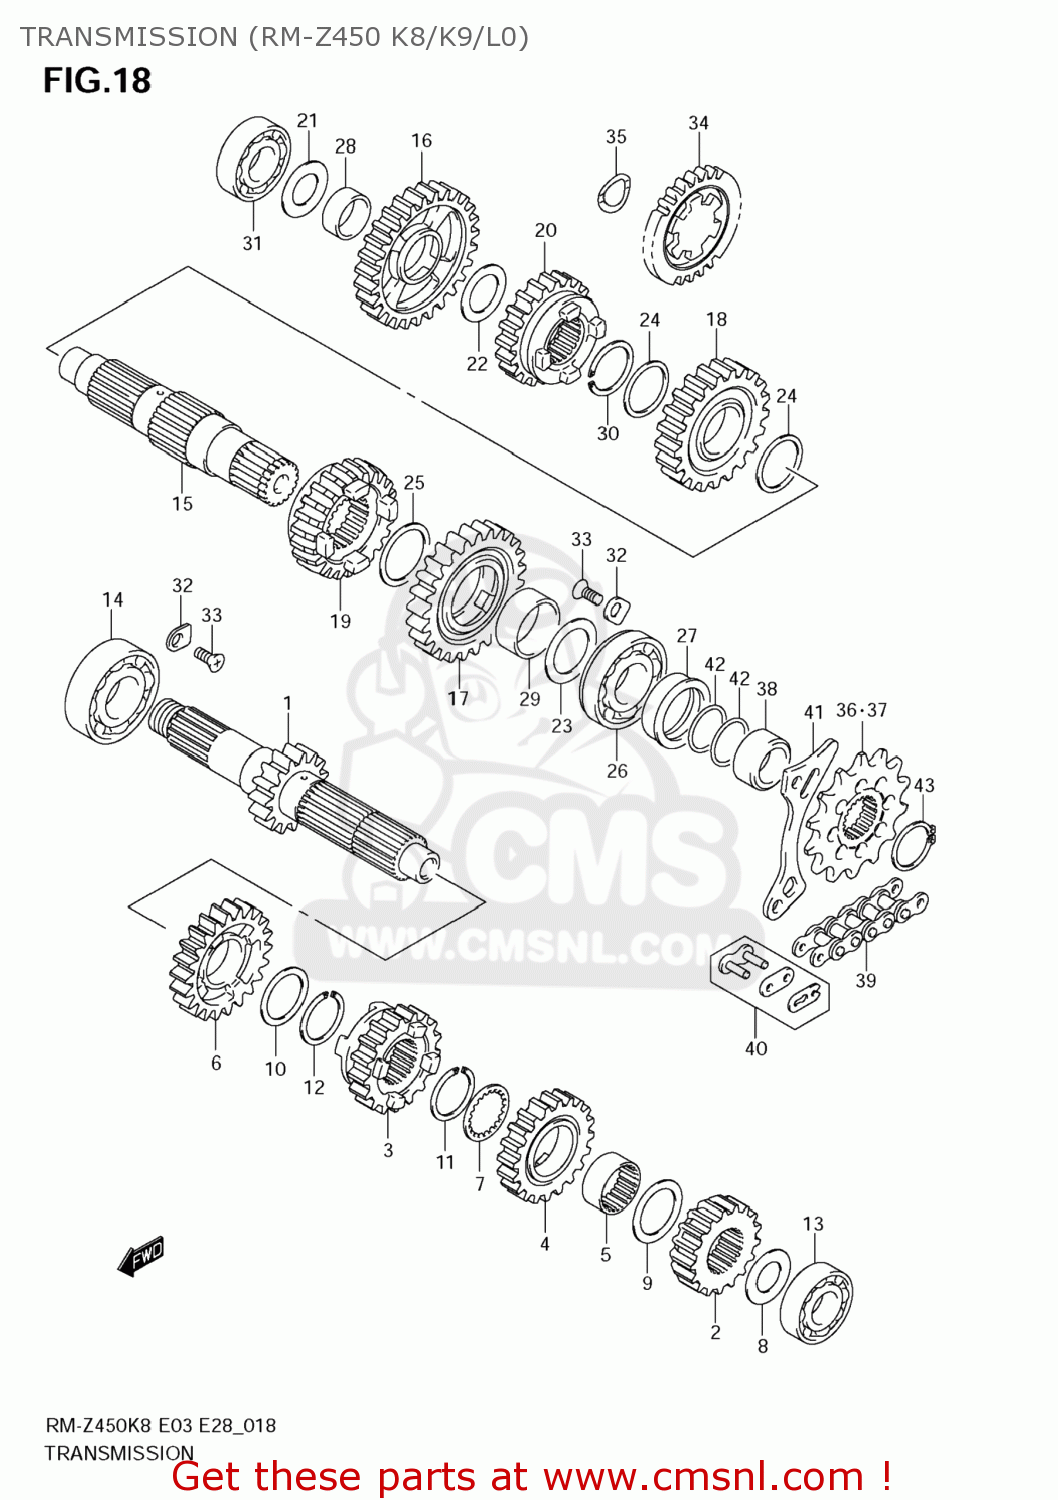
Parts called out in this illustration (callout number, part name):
1	SHAFT,COUNTER
2	GEAR,2ND DRIVE
3	GEAR,3RD DRIVE
4	GEAR,4TH DRIVE
5	BUSH,4TH DRIVE GEAR
6	GEAR,5TH DRIVE
7	WASHER,LOCK
8	SHIM(17X30X1)
9	SHIM(25X34X1)
10	SHIM(25X32X1)
11	CIRCLIP
12	CIRCLIP
13	BEARING
14	BEARING
15	SHAFT,DRIVE
16	GEAR,1ST DRIVEN
17	GEAR,2ND DRIVEN
18	GEAR,3RD DRIVEN
19	GEAR,4TH DRIVEN
20	GEAR,5TH DRIVEN
21	SHIM(17X30X1)
22	SHIM(20X30X1)
23	SHIM(24X34X1)
24	SHIM(25X30X1)
25	SHIM(27X33X1)
26	BEARING(24X56X14)
27	SEAL,OIL(31X40X6.7)
28	BUSH(20X24X10)
29	BUSH(27X31X13)
30	CIRCLIP
31	BEARING
32	RETAINER,COUNTER BEARING,R
33	SCREW(6X12)
34	GEAR,KICK STARTER IDLE
35	WASHER,KICK IDLE
36	SPROCKET,ENGINE(NT:13)
37	SPROCKET,ENGINE(NT:14)
38	SPACER,ENGINE SPROCKET
39	CHAIN,DRIVE
40	JOINT SET,CHAIN
41	PLATE,FR CHAIN GUIDE
42	O RING(D:1.9,ID:21.8)
43	CIRCLIP
